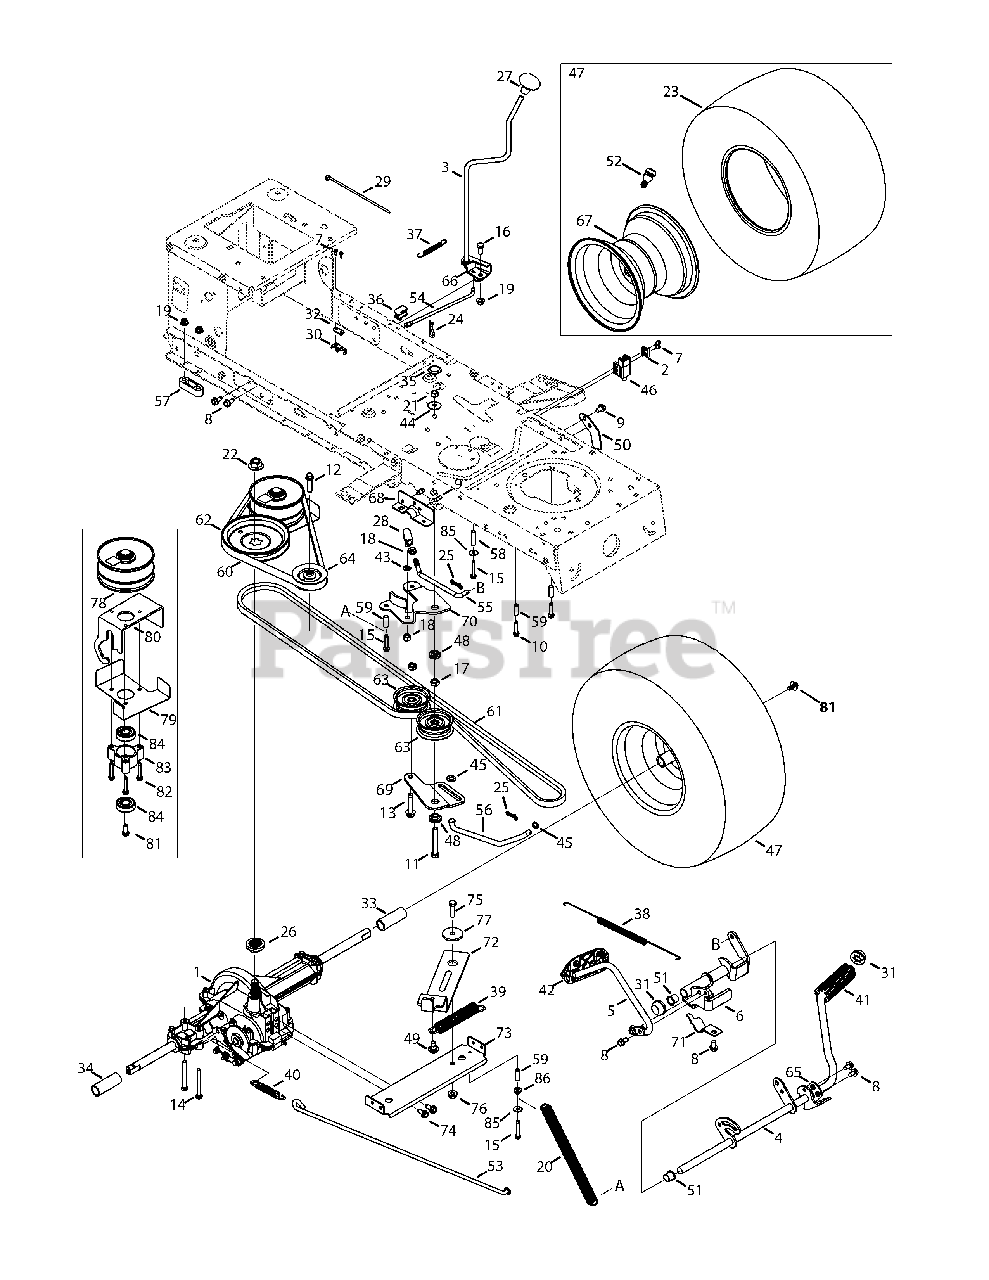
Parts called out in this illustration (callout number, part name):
1	Transmission Drive Assembly
2	Plate Switch
3	Shaft Lever Assembly
4	Pedal Assembly, drive
5	Pedal Assembly, control
6	Pedal Bracket Assembly
7	Screw, 8-18:0.500
8	Screw, 5/16-18 x .750
9	Screw, 5/16-18 x 0.625
10	Screw, 1/4-20 x 1.250
11	Hex Screw, 3/8-16 x 2.50
12	Screw, 3/8-16 x 1.500
13	Screw, 3/8-16 x 1.750
14	Hex Screw, 5/16-18 x .625
15	Screw, 1/4-20 x 1.75
16	Hex Screw, 5/16-18 x .75
17	Jam Nut, 7/16-20
18	Hex Nut, 3/8-24
19	Flangelock Nut, 5/16-18
20	Spring Extension, 1.0 OD x 11.125
21	Nut, 3/8-16, Centerlock
22	Flange Nut, 9/16-18
23	Tire, 20 x 8 x 8 Rd. Sh.
24	Cotter Pin INT- .125 DIA
25	Bow-Tie Cotter Pin, 72
26	Pulley Hub, 5/8 SPLINE
27	Shift Knob
28	Ball joint
29	Cable tie
30	Short Spring Switch
31	Push Cap, 5/8
32	Plate Insulator Nut
33	Sleeve, .758 x .821 x 3.3125
34	Sleeve, .758 x .821 x 2.4375
35	Plug, 7/8
36	Shift Plate Bearing
37	Spring Extension, .38 OD x 3.25 LG
38	Spring Extension, .70 OD X 12.00
39	Spring Extension, .97 Od X 6.18 Lg
40	Spring Extension, .59 OD x 4.00 LG
41	Foot Pad, 4.0 Long
42	Control Pad
43	Lock Washer 3/8
44	Flat Washer, .406 x 1.920 x .060
45	Flat Washer, .375 X .738 X .063
46	Switch Interlock
47	Wheel Assembly, 20 x 8 x 8 Rd. Sh.
48	Shoulder Spacer, 1.00 X .38 X .38
49	Shoulder Screw, .43 x .29, 5/16-18
50	Stop Pedal Plate
51	Flng Bearing .63 Id x .695 Od X .60
52	Valve, tubeless Air
53	Brake Rod
54	Shift Rod, 46"
55	Idler Adjustment Rod
56	Transmission Bypass Rod
57	Spacer, T-Axle .68
58	Spacer, .260 X .372 X 1.420 Lg
59	Spacer, .260 X .375 X 1.030 Lg
60	V Belt, 5L 40.9 Poly
61	V Belt, 5L, 90.93 Poly
62	V Pulley 7.25 DIA SPUN
63	Idler Pulley
64	Idler Pulley
65	Pedal Support Bracket
66	Shaft Adjust Bracket
67	Rim Assembly
68	Frame Pedal Bracket, Rh
69	Center Idler Bracket
70	Idler Bracket
71	Pedal Support Bracket
72	Idler Bracket Assembly
73	Bracket Assembly
74	Screw, 5/16-18 x 0.750
75	Hex Screw, 3/8-16 x 1.25
76	Flangelock Nut, 3/8-16
77	Shoulder Spacer, .8840 X .190
78	Variable Speed Pulley Assembly
79	Belt Keepr Assembly
80	Bracket Assembly
81	Screw, 5/16-24 x .750
82	Screw, 1/4-20 x 1.500
83	Bearing Cup
84	Ball Bearing, 17 x 40 x 12
85	Flat Washer, .260 x .720 x .060
86	Shoulder Spacer, .375 x .625 x .20
